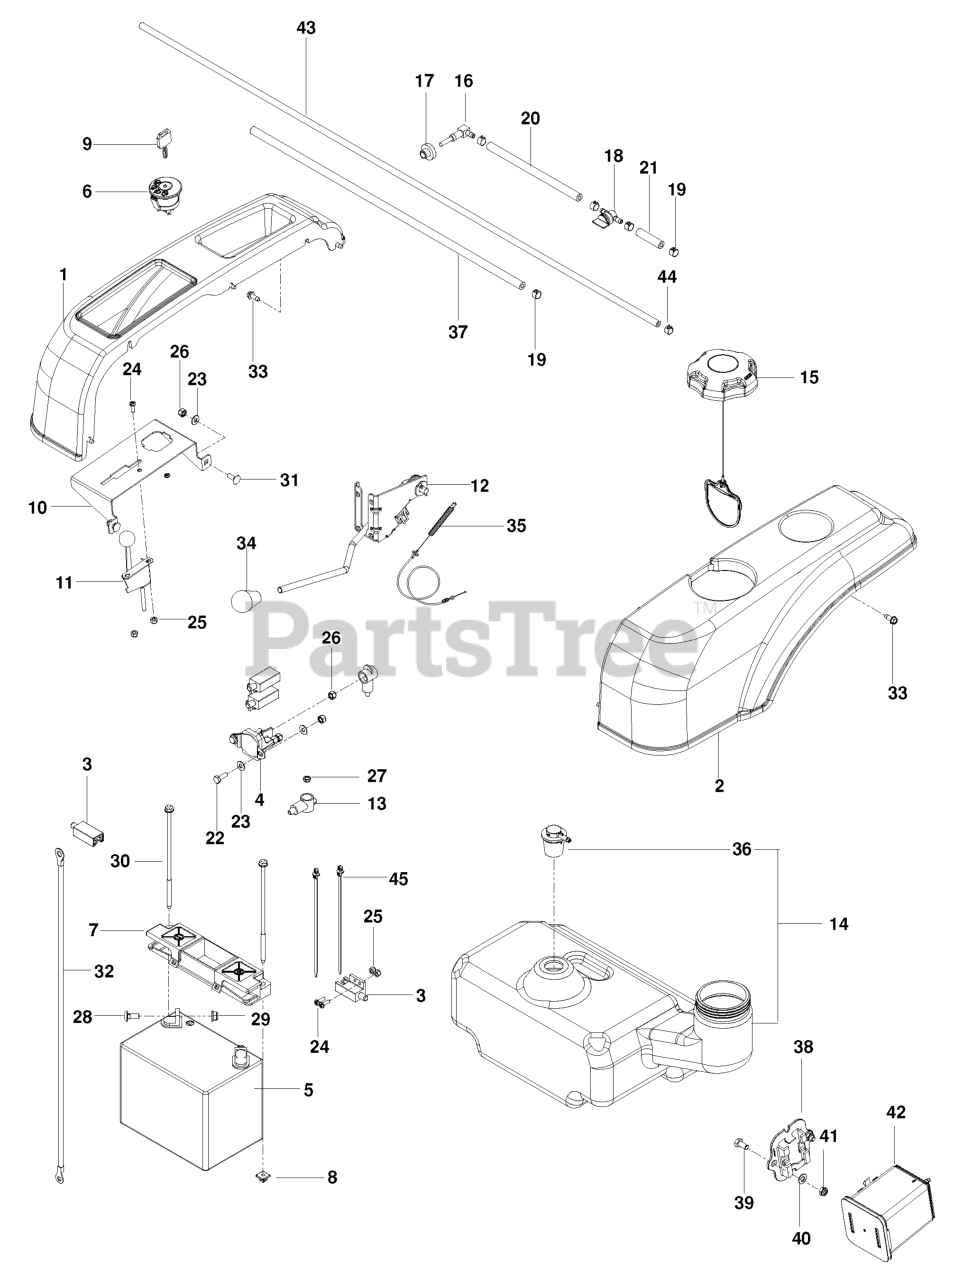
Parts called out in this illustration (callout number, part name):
1	FENDER, RZ 30/38 RT
2	FENDER, RZ 30/38 LT
3	SWITCH, INTERLOCK
5	BATTERY, 12 V 330 AMP
6	RP IGNITION SWITCH
7	BATTERY HOLD DOWN
8	PUSH NUT-NYLON
9	KEY
10	MOUNT, CONTROLS, BLK
11	CABLE, THROTTLE
12	ASM, CLUTCH ENGAGE W/CABLE
13	TERMINAL COVER-SM
14	ASSEMBLY, FUEL TANK, CALIF
15	CAP, FUEL
16	ELBOW W/FILTER
17	TANK FITTING
18	FUEL VALVE
19	HOSE CLAMP
20	HOSE 1/4 X 8
21	HOSE 1/4 X 2"
22	HCS 1/4C X 3/4 HCS
23	WASHER 1/4 SAE
24	SCREW #10-24 X 5/8
25	NUT 10-24 NYLOC
26	NUT.1/4-20.HEX.NYLOC.ZD
27	JAM NUT 1/4C (2 2 PW01)
28	BOLT 5/16C X 3/4" CARRIAGE
29	5/16-18 NYLOC FLANGE NUT
30	BOLT - 1/4-20 X 7.5
31	RHSNB 1/4C X 3/4
32	BATTERY CABLE, NEGATIVE
33	SCREW 1/4 X 5/8
34	KNOB - SHIFT
35	CABLE.CLUTCH.38".SERVICE
36	VALVE, ROLLOVER, GROMMET
37	FUEL LINE 24"
38	BRACKET, CANISTER
39	HCS 5/16-18 X 5/8 GR 5 ZD
40	FLAT WASHER 5/16 SAE
41	5/16-18 THIN PROF NY
42	CANNISTER, CARBON
43	HOSE, FUEL 3/16" X 42"
44	CLAMP, HOSE
45	TIE, PLASTIC
